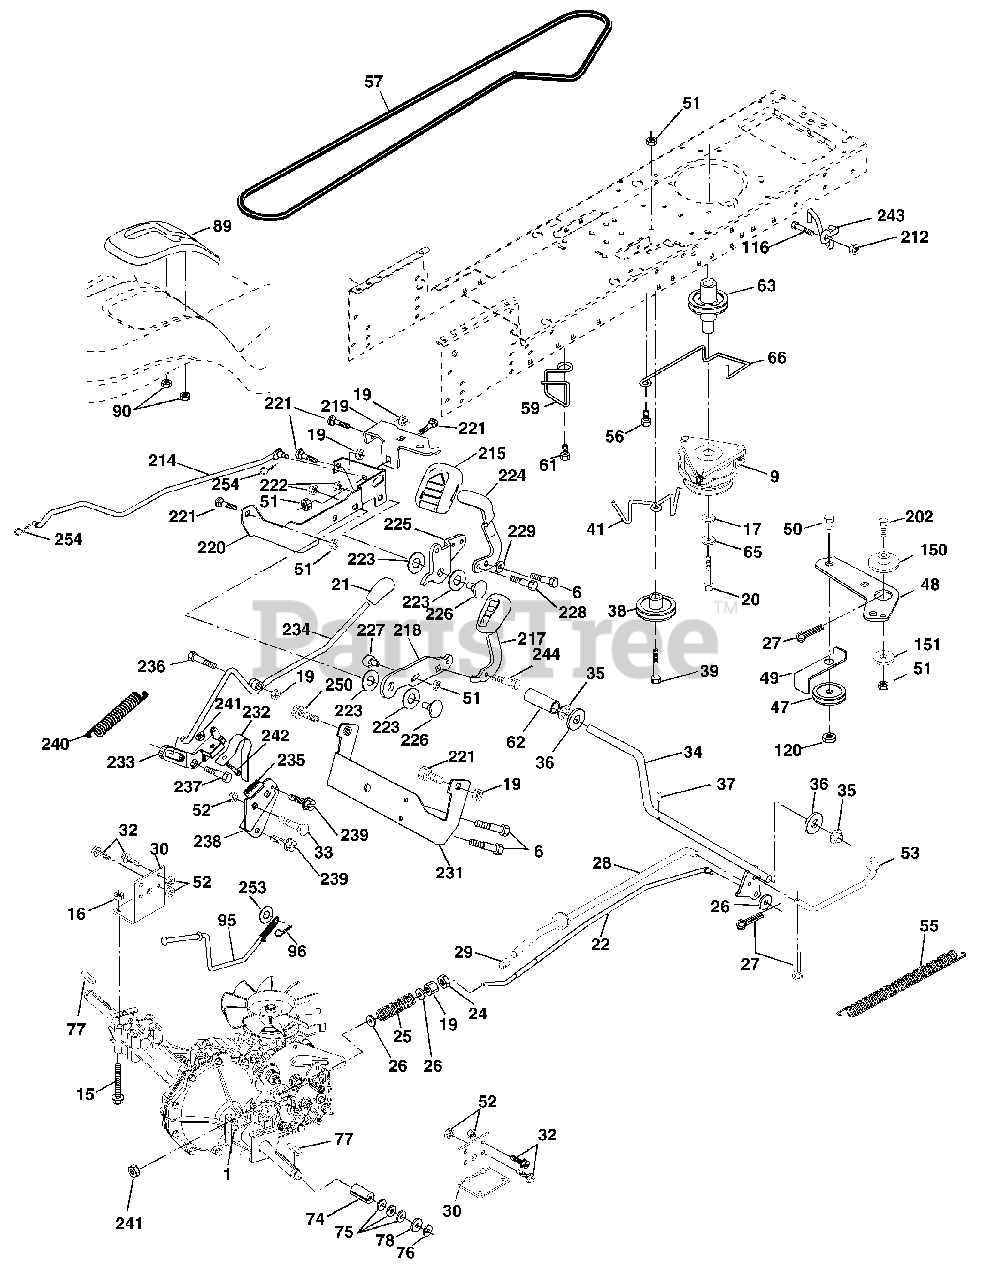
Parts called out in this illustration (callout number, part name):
6	Screw 5/16-18 x 3/4
9	Clutch Elec
15	Bolt Hex Flghd 5/16-18 Gr. 5
16	Nut Lock Hex W/Ins. 5/16-18 Unc
17	Washer 1-1/2 OD x 15/32 ID x .250
19	Nut Lock Hex W/Wsh 3/8-16 Unc
20	Bolt Hex 7/16-20 x 4 x Gr. 5-1.5
21	Knob Custom Control Cruise
22	Rod, Brake
24	Nut, Hex Jam 3/8-16 Unc
25	Spring, Brake Rod
26	Washer
27	Pin Cotter 1/8 x 3/4 CAD.
28	Rod, Parking Brake
29	Cap, Brake, Park
30	Bracket, Transaxle
32	Bolt Hex Hd 5/16-18 Unc x 3/4
33	Bolt Rdhd Sqnk 5/16-18 Unc x 3/4
34	Shaft, Foot Pedal
35	Bearing, Nylon
36	Washer
37	Pin, Roll
38	Pulley, Composite, Flat
39	Bolt Fin Hex 3/8-16 Unc x 3
41	Keeper, Belt Idler Flat
47	Pulley, Idler, V-Groove
48	Bellcrank Clutch Grnd Drw Stl
49	Retainer, Belt
50	Bolt
51	Nut Crownlock 3/8-16 UNC
52	Nut, Crownlock 5/16-18 Unc
53	Link, Clutch
55	Spring, Return, Clutch
56	Screw 3/8-16 x 1.0
57	V-Belt, Ground Drive
59	Keeper, Center Span
61	Screw 3/8-16 x .875
62	Cover, Pedal
63	Pulley, Engine
65	Washer
66	Keeper Belt Engine
74	Spacer, Axle
75	Washer 25/32 x 1-1/4 x 16 Ga.
76	E-Ring
77	Key, Square
78	Washer 25/32 x 1-5/8 x 16 Ga.
89	Console, Shift
90	Nut Self-Thd Wsh-hd 1/4 Zinc
95	Rod Bypass
96	Retainer Spring 1" Zinc/Cad
116	Bolt RDHD SQNK 3/8-16 Unc x 1
120	Nut Lock Flg 3/8-16 Unc
150	Spacer Retainer
151	Washer 13/32 x 2 x 10 Ga.
202	Bolt Carr Sh 3/8-16 x 1-1/2 Gr. 5
212	Nut Hex Flange Lock
214	Link Transaxle
215	Cover Pedal Forward
217	Pedal Reverse
218	Arm Control Pedal Reverse
219	Bracket Frest Pdl Ctrl. Hyd
220	Bracket Mtg. Pedal Control
221	Bolt Rdhd Sqnk 3/8-16 Unc x 3/4
222	Nut Crownlock 7/16-14 Unc
223	Washer Nylon 11/16 ID x .060
224	Pedal Forward
225	Arm Control Pedal Forward
226	Bolt Pivot Spacer
227	Cam Reverse Pedal LT
228	Bolt Shoulder 5/16-18
229	Washer Serrated 5/16 x .75
231	Strap Torque
232	Actuator Cruise Disengage
233	Pawl Control Cruise
234	Lever Control Cruise
235	Sector Control Cruise
236	Bolt Shoulder 3/8-16 Unc 1/44
237	Bolt Shoulder 5/16-18
238	Arm Mtg. Cruise Sector
239	Screw Thdrol 5/16 x 1/2
240	Spring Return Cruise Control
241	Nut Centerlock 1/4-20 Unc
242	Bolt Fin Hex 1/4-20 Unc x .75
243	Bracket Anti-Rotation CVX
244	Screw 5/16-18 x 5/8
250	Screw 3/8-16 x .75
253	Washer .3125 x .615 x 16 Ga.
